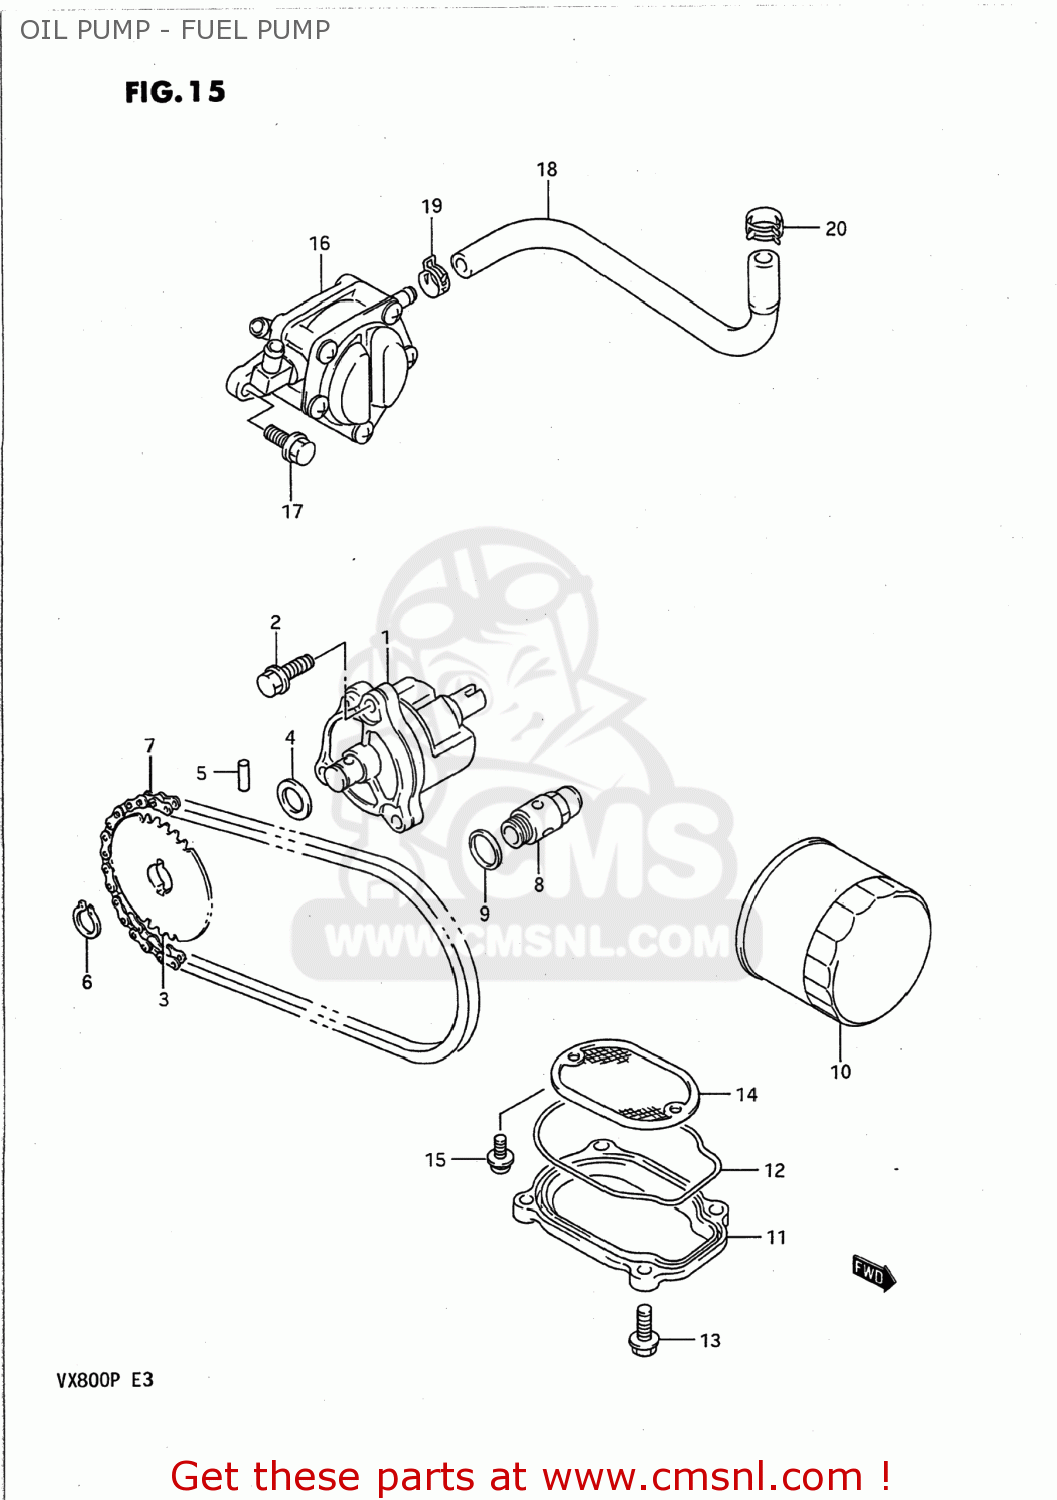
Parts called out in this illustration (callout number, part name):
1	PUMP ASSY,ENGINE OIL
2	BOLT 6X25
3	SPROCKET,OIL PUMP DRIVEN
4	SHIM
5	PIN(5X18)
6	CIRCLIP,12 MM
7	CHAIN,OIL PUMP DRIVE
8	VALVE ASSY,OIL RELIEF
9	GASKET(16X22X2) (NAS)
10	FILTER,OIL
11	CAP,OIL STRAINER
12	O RING,OIL STRAINER CAP
13	BOLT 6X20
14	STRAINER,ENGINE OIL
15	SCREW
16	PUMP ASSY,FUEL
17	BOLT
18	HOSE(5.4X11.4X600)
19	CLIP
20	CLAMP
